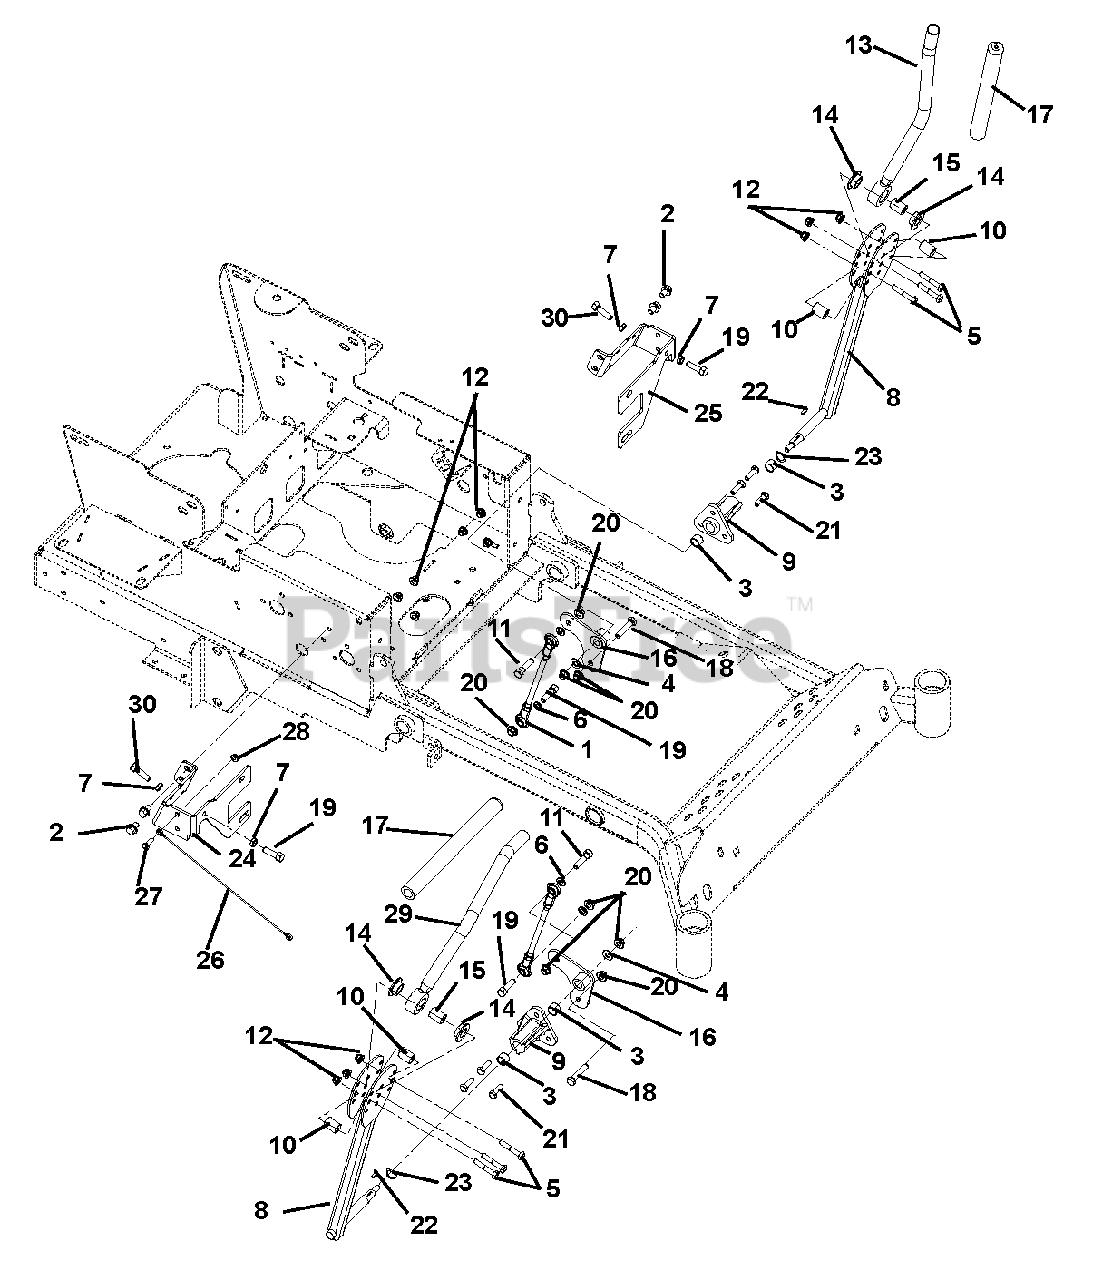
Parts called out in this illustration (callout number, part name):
1	Assembly, Steering Linkage
2	Screw, Tapping .38-16 x .50 Hex Washer Head
3	Bushing .625 x .75 x .50
4	Washer, Flat Steel .406 x .812 x .065
5	Bolt, Hex .31-18 x 1.75 Grade 5
6	Washer, Locking .38 x .094
7	Nut, Hex Jam .375-16
8	Control Arm
9	Housing, Bushing
10	Eccentric
11	Bolt, Hex .38-16 x 1.50 Grade 5
12	Nut, Nyloc Flange .375-16
13	Handle Weldment Left-Hand
14	Bushing, Flange Nylon .762 x 1.48 x .44
16	Bracket, Lift Assist Spring Mounting
17	Grip, Handlebar
18	Bolt, Hex .375-16 x 1.75
19	Bolt, Hex .38-16 x 1.25 Grade 5
20	Nut, Nyloc Flange 3/8-16
21	Bolt, Hex .31-18 x 1.00 Grade 5
22	Key, Woodruff .13 x .63
23	Wave Washer
24	Stop, Steering-Right Hand
25	Stop, Steering-Left Hand
26	Cable, 12.0 LANYARD, Nylon
27	Bolt-Hex .25-20 x .75 Grade 5
28	Nut, Nyloc Flange .25-20
29	Handle Weldment Right-Hand
30	Bolt, Hex .38-16 x .75 Grade 5
